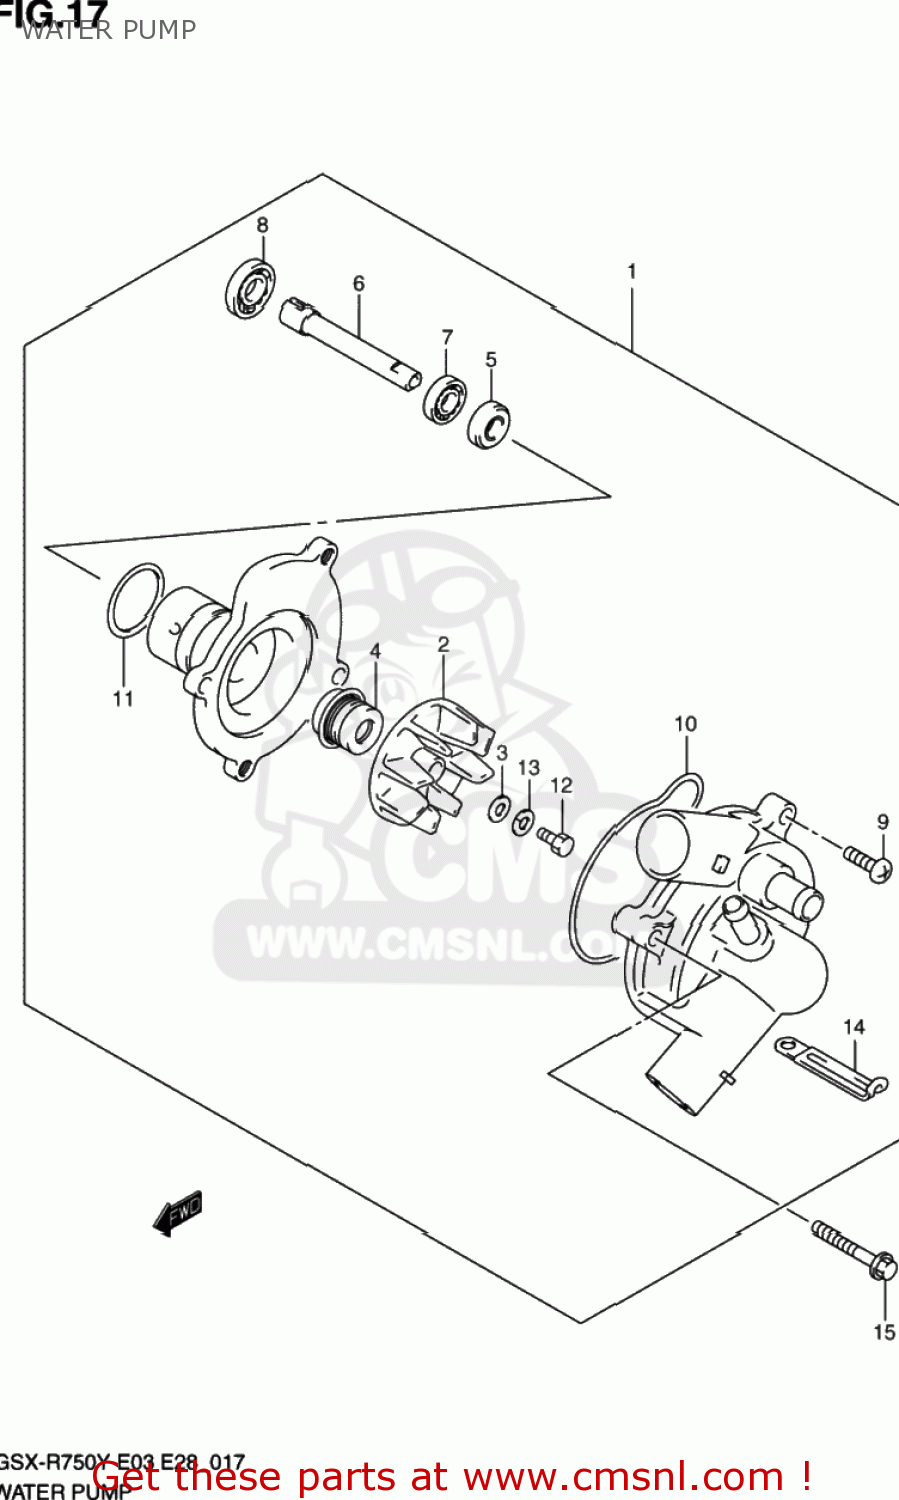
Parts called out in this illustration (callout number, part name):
1	PUMP ASSY,WATE
2	IMPELLER
3	GASKET(6X15X2.2) (NAS)
4	SEAL,MECHANICAL
5	SEAL,OIL(10X21X5)
6	SHAFT
7	BEARING(10X26X8)
8	BEARING(12X28X8)
9	SCREW 6X16
10	O RING
11	O RING,WATER PUMP HOLDER
12	BOLT(6X13)
13	WASHER
14	CLAMP(L:65)
15	BOLT
